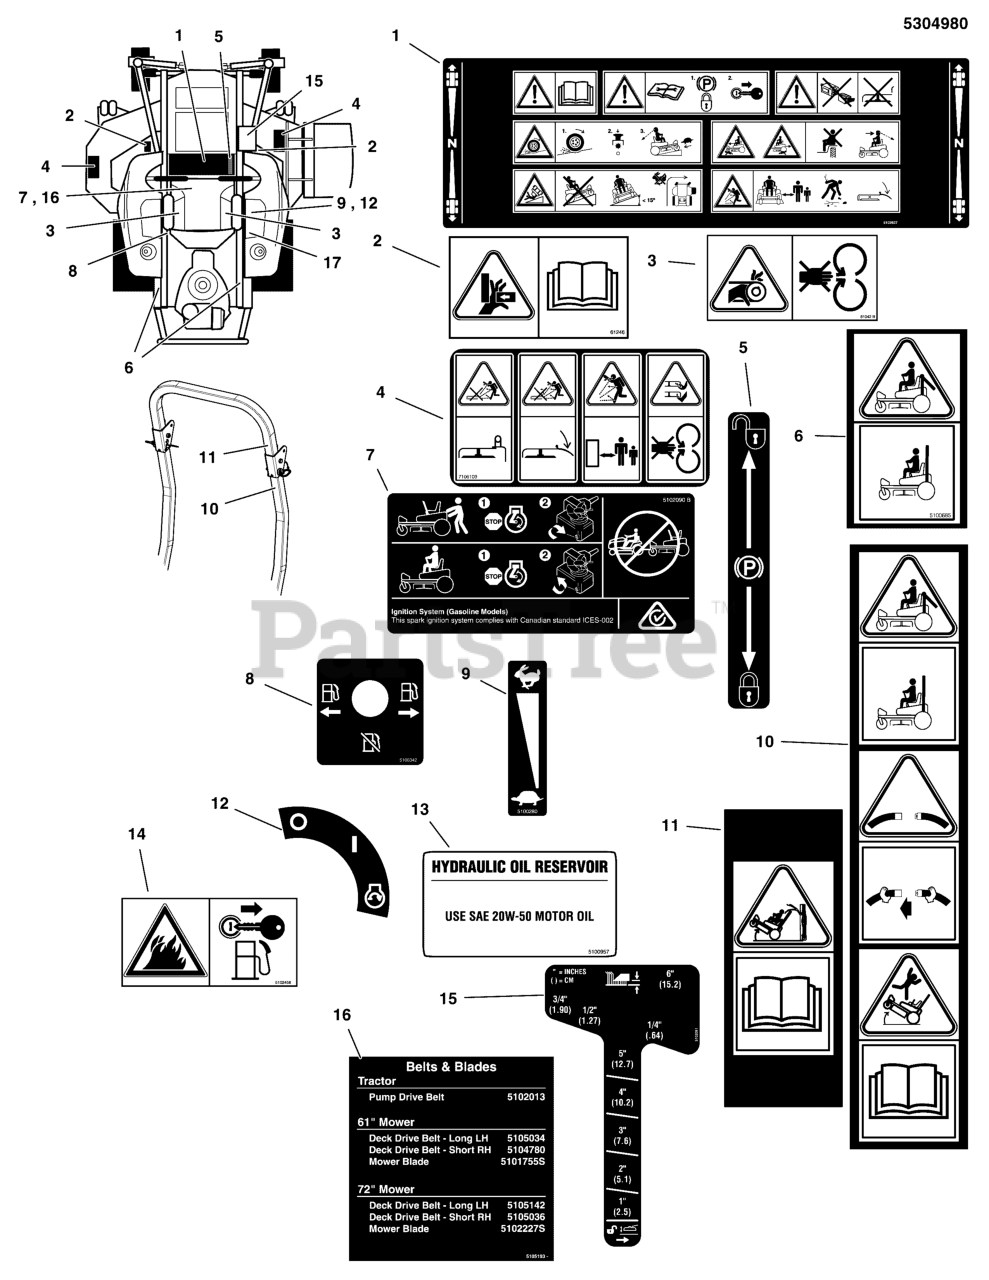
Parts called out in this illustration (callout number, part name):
1	DECAL, MAIN SAFETY, ANSI CE
2	DECAL, PINCH POINT, CE
3	DECAL, CE DANGER
4	DECAL, DISCHARGE SAFETY, EXPORT
5	DECAL, PARKING BRAKE SYMBOLS
6	DECAL, WARNING, ROLL BAR, CE
7	DECAL, TRANSAXLE RELEASE, S200XT
8	DECAL, FUEL VALVE
9	DECAL, THROTTLE CONTROL
10	DECAL, SAFETY, CE ROPS
11	DECAL, SAFETY, CE ROPS, OBS
12	DECAL, IGNITION SWITCH
13	DECAL, HYDRAULIC OIL, 20W50
14	DECAL, FIRE ANSI EXPORT
15	DECAL-HEIGHT CITATION
16	DECAL, BELT & BLADE S200XT, F210Z, 2BELT
